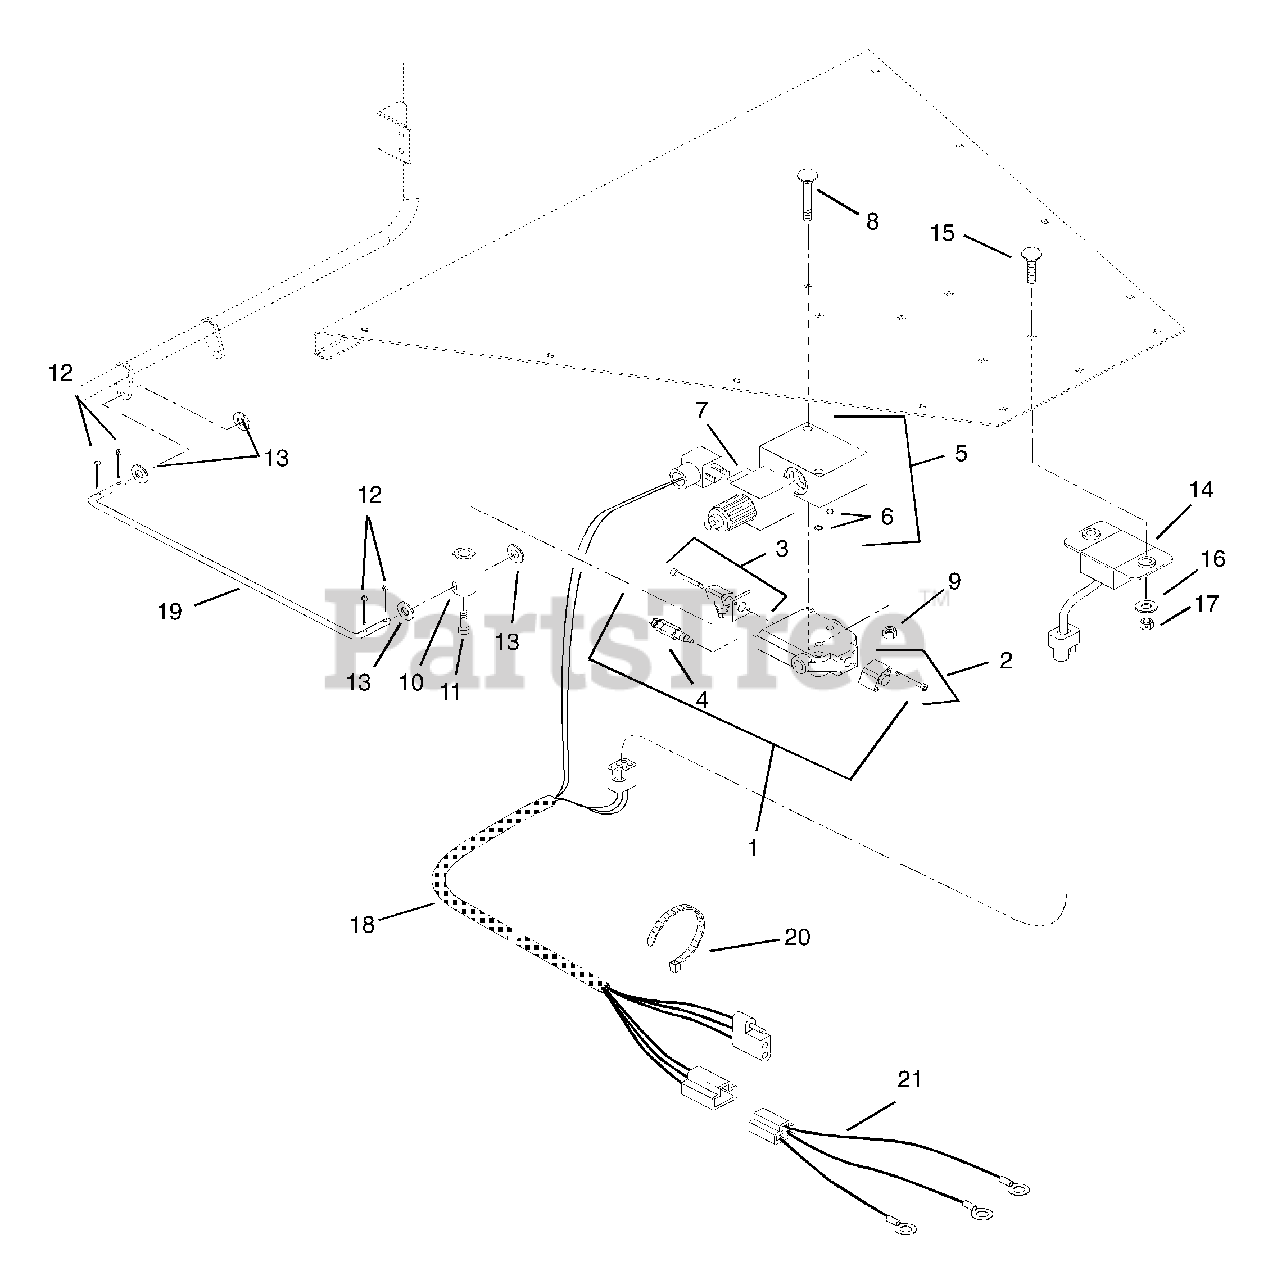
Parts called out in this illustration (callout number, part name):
1	Valve-Hydraulic
1	Valve-Directional Control Module
2	Detent Assembly-Hydraulic Control Valve
3	Lever Assembly-Hydraulic Control Valve
4	Relief Valve Assembly-Hydraulic Control Valve
5	Valve Base Assembly-Flow Control
6	O-Ring .375 x .504 x .070
7	Valve-Cartridge -Flow Control
8	Bolt-Round Head Square Neck .31-18 x 2.75
8	Bolt-Round Head Square Neck .31-18 x 4.00
9	Nut-Locking-Center .31-18
10	Hex Adapter
11	Screw-Socket Head M8 x 1.25 x 20mm
12	Pin-Cotter .156 x 1.00
13	Washer-Flat-Steel .438 x 1.00 x .083
14	Module-Load Control
15	Bolt-Round Head Square Neck .25-20 x 1.00 Grade 5
16	Washer-Flat-Steel .312 x .734 x .065
17	Nut-Locking-Center .25-20
18	Harness-Wiring Autofeed
19	Rod-Valve Control
20	Cable Tie
21	Harness-Adapter Autofeed
